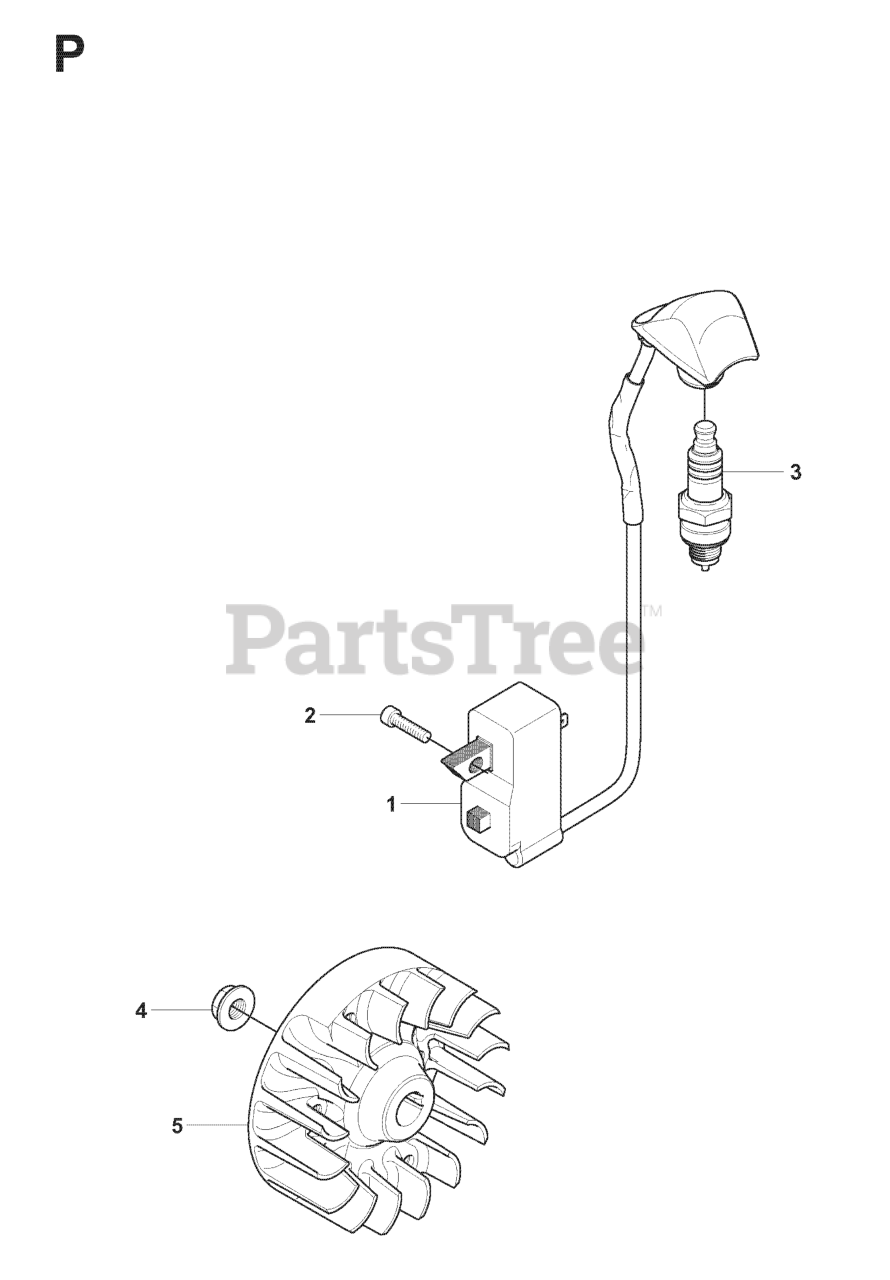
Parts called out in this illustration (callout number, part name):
1	IGNITION MODULE DM60CWS
3	SPARK PLUG M14X1.25 NGK BPMR7A
4	FLANGE NUT
5	FLYWHEEL
